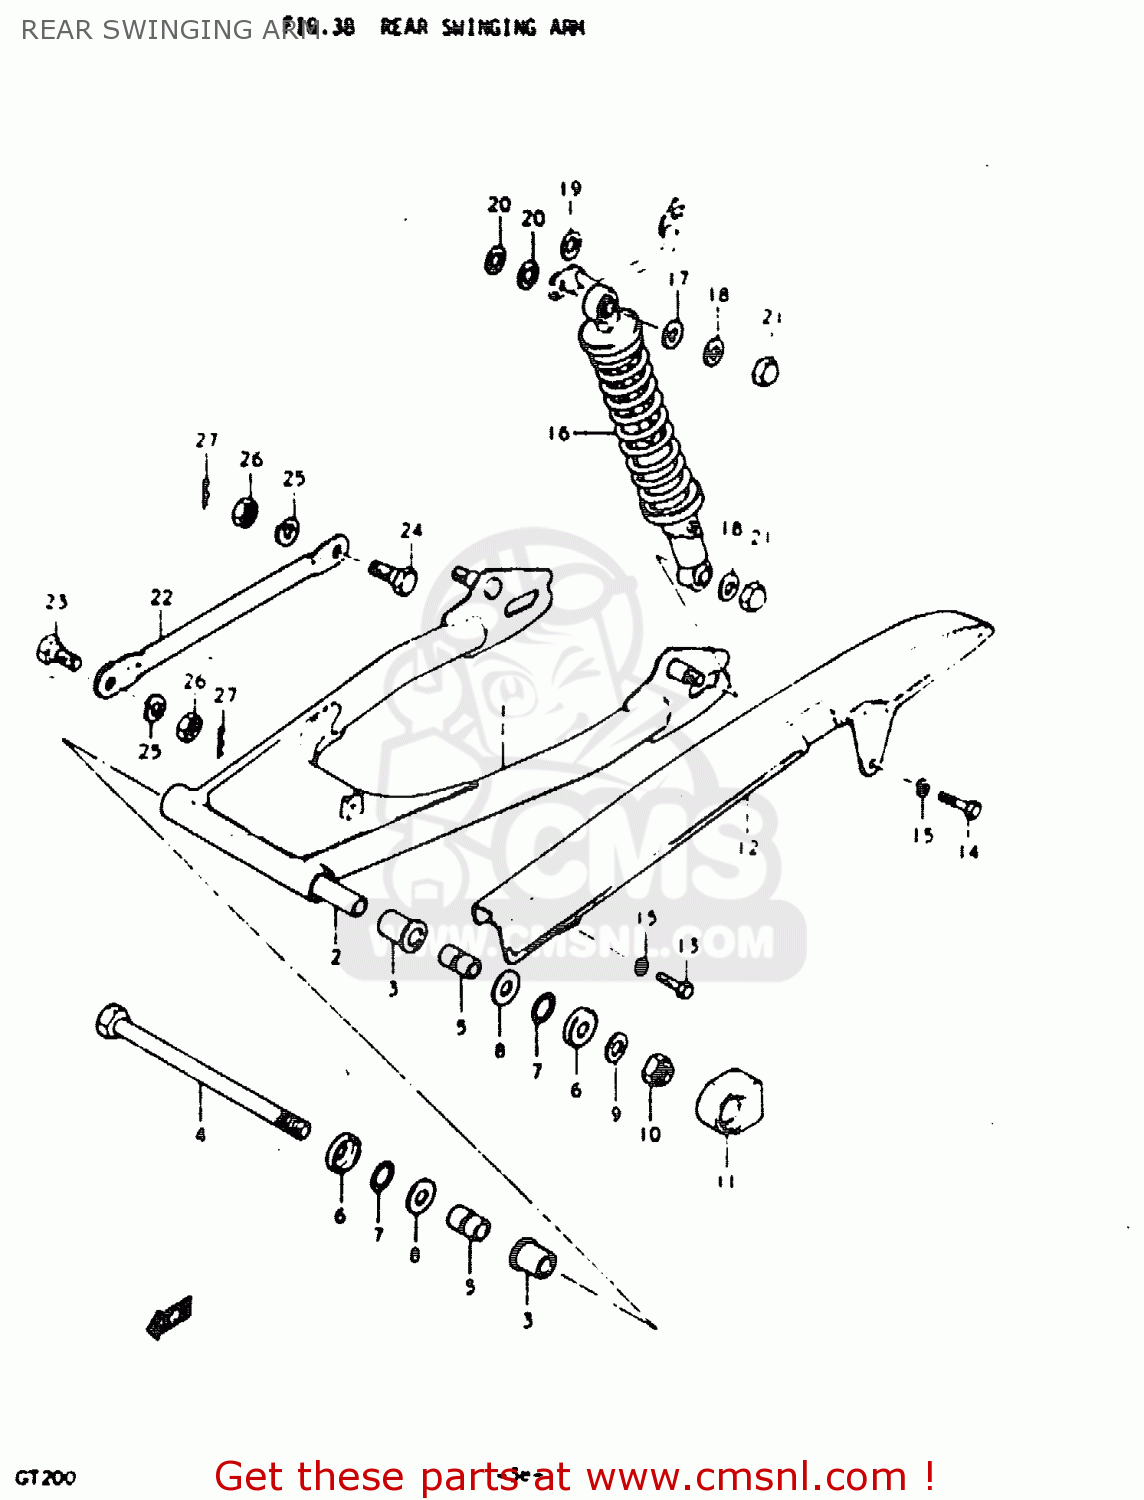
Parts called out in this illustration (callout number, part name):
1	REAR SWINGING ARM SET
2	SPACER,SWING ARM,CENTER
3	BUSH
4	SHAFT, PIVOT
5	SPACER,RR SWGARM PIVOT
6	COVER,SWGARM BUSH DUST SEAL
7	O RING(D:2,ID:24.5)
8	WASHER(12.5X24X2.3)
9	WASHER
10	NUT 12MM
11	BUFFER,CHAIN TOUCH DEFLECTOR
12	CHAIN CASE
13	BOLT
14	BOLT
15	LOCK WASHER
16	SHOCK ABSORBER ASSY, REAR
17	WASHER(10.5X24X3.2)
18	WASHER
19	WASHER (12.5X24X3.2)
20	WASHER
21	NUT, LOWER LH
22	TORQUE LINK, REAR
23	BOLT(8X22.5)
24	BOLT
25	LOCK WASHER
26	NUT
27	CLIP
